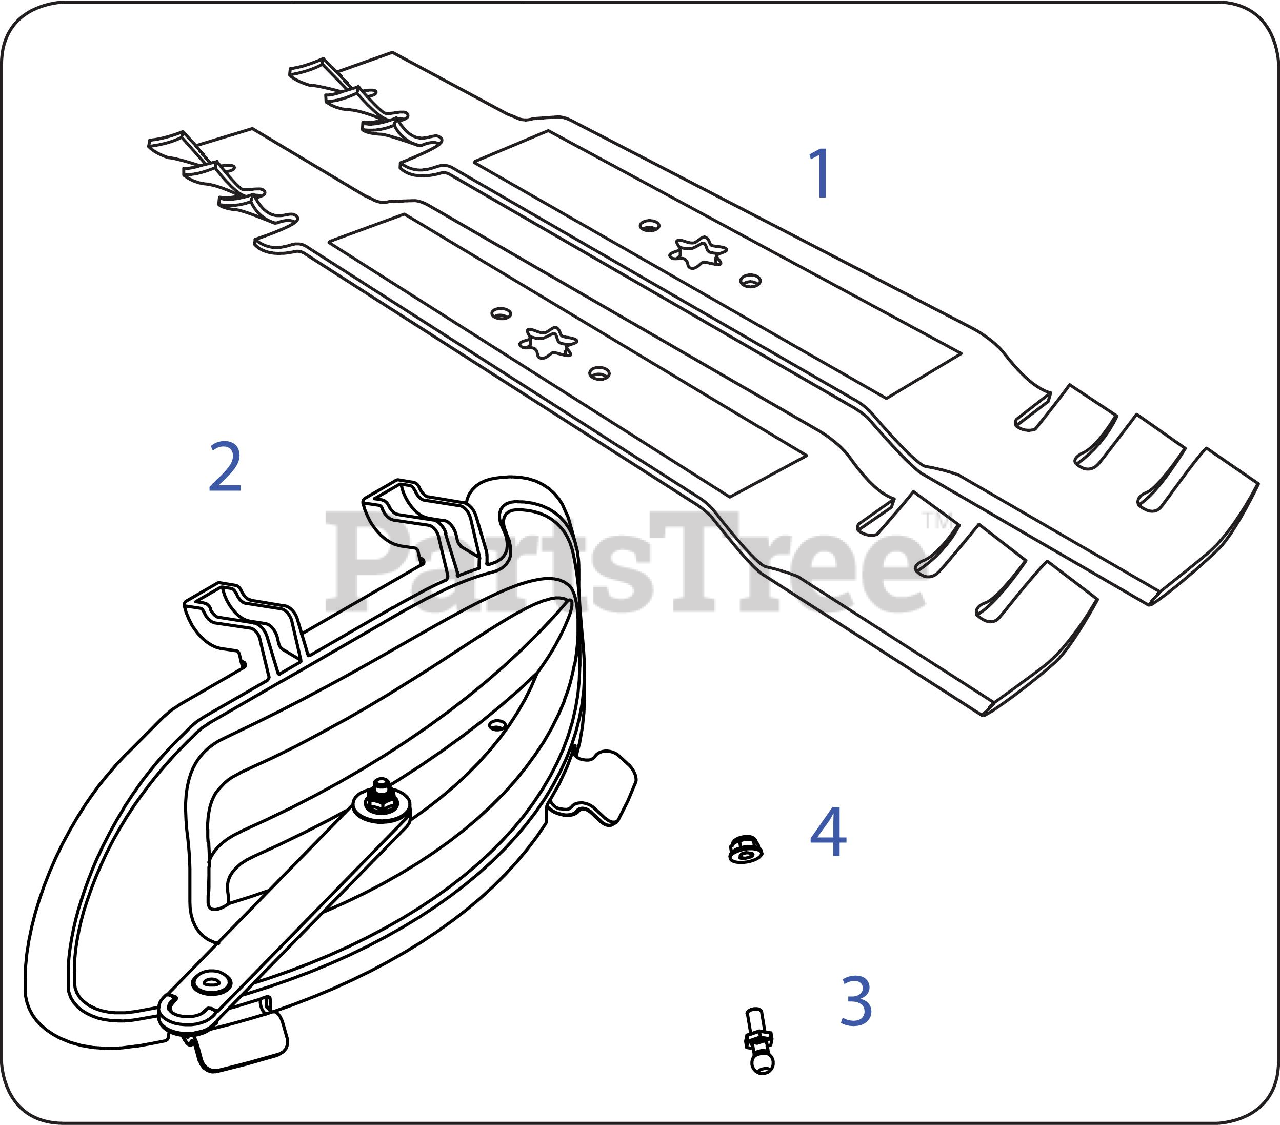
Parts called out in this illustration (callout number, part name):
1	21.23" Blade (Mulch)
2	Mulch Plug Assembly
3	Grass Catcher Pin
4	Flange Lock Nut
